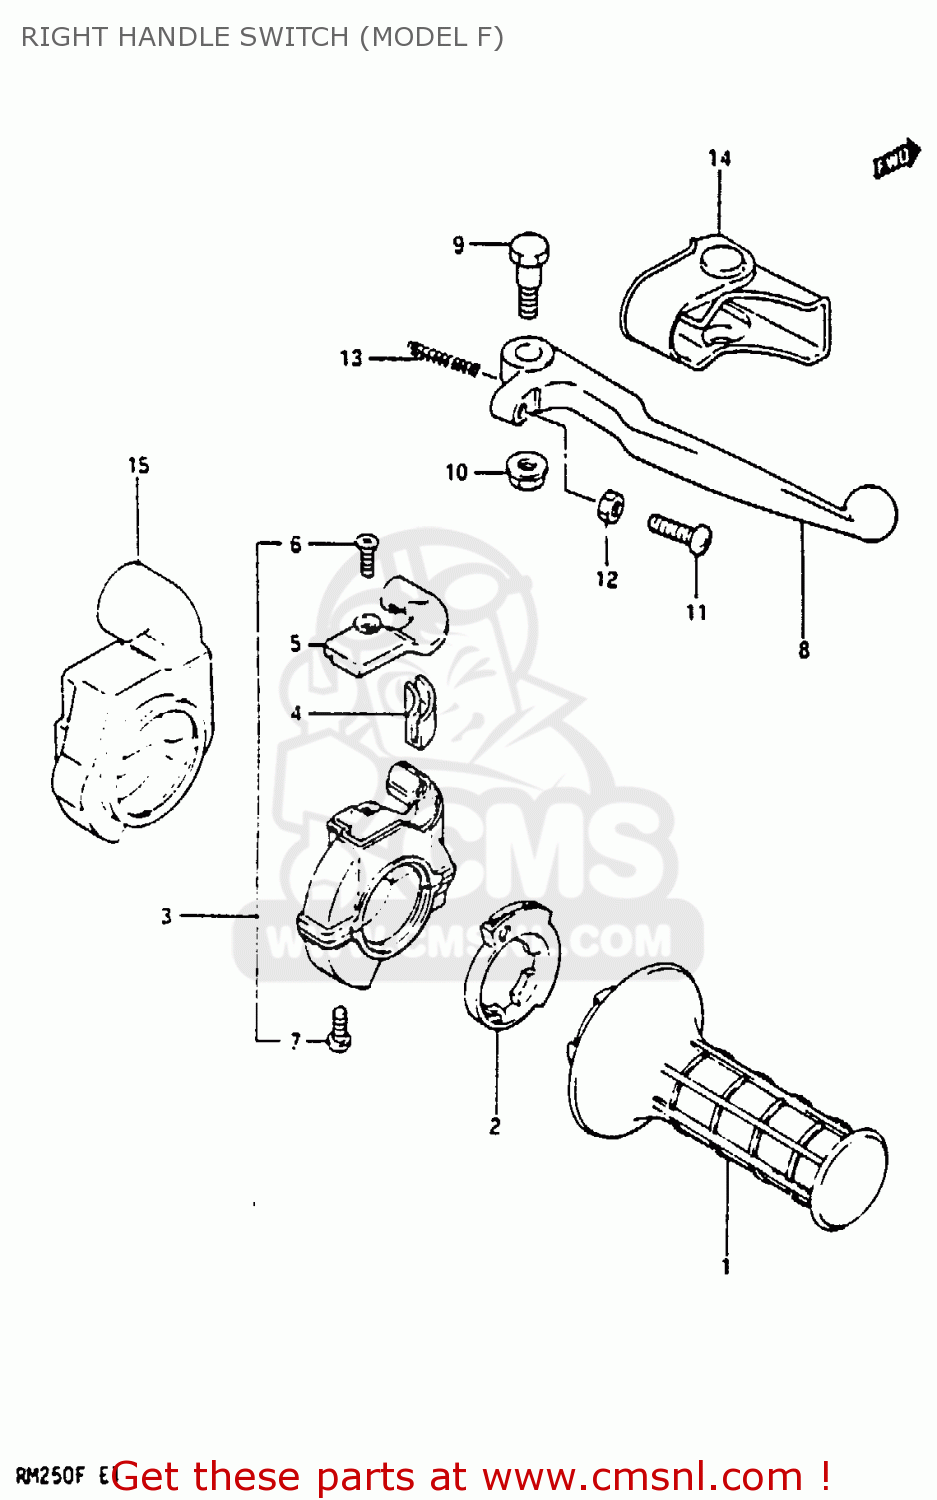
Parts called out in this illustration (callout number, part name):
1	GRIP,THROTTLE
2	ROTOR,THROTTLE GRIP
3	CASE ASSY,THROTTLE
4	GUIDE PIECE,THROTTLE
5	COVER,THROTTLE CASE
6	SCREW
7	SCREW
8	LEVER,BRAKE
9	BOLT,BRAKE LEVER
10	NUT,BRAKE LEVER
11	BOLT,LEVER
12	NUT ,5MM
13	SPRING,RETURN
14	COVER,BRAKE LEVER
15	COVER,THROTTLE CASE
